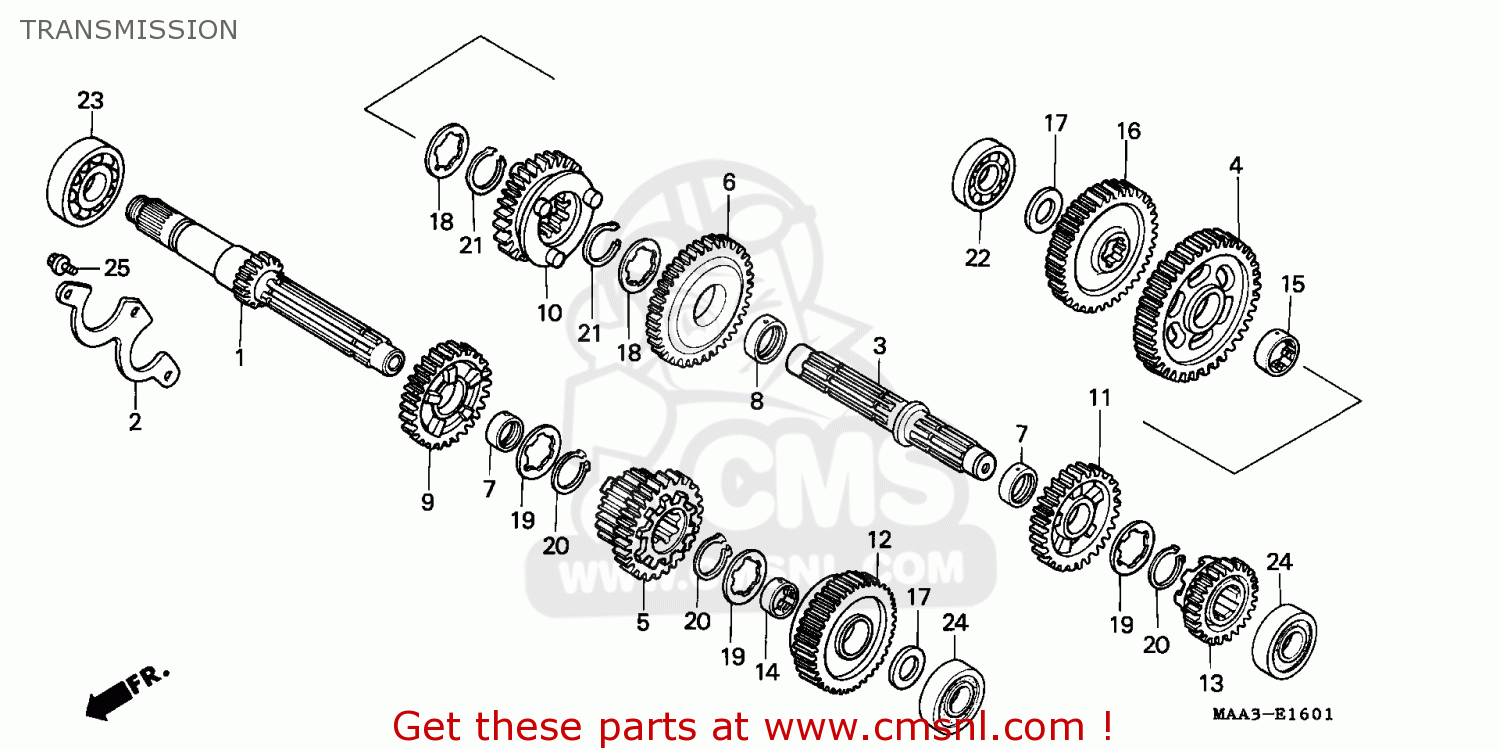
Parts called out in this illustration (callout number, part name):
1	SHAFT,MAIN
2	PLATE,BEARING
3	SHAFT COMP,COUNTE
4	GEAR,C-1
5	GEAR,M-2 M-4
6	GEAR,C-2
7	COLLAR 28MM
8	COLLAR,30X11.2
9	GEAR,M-3
10	GEAR,C-3
11	GEAR,C-4
12	GEAR,M-5
13	GEAR,C-5
14	COLLAR,SPLINE 28X
15	COLLAR,SPLINE 30X
16	GEAR,FINAL DRIVE
17	WASHER,20X37X2
18	WASHER,THRUST 30M
19	WASHER,THRUST,28
20	CIR CLIP,28MM
21	CIRCLIP,30MM
22	B/BRG RAD N/COM
23	B/BRG RAD N/COM
24	B/BRG RAD N/COM
25	BOLT,FLANG,6X16
